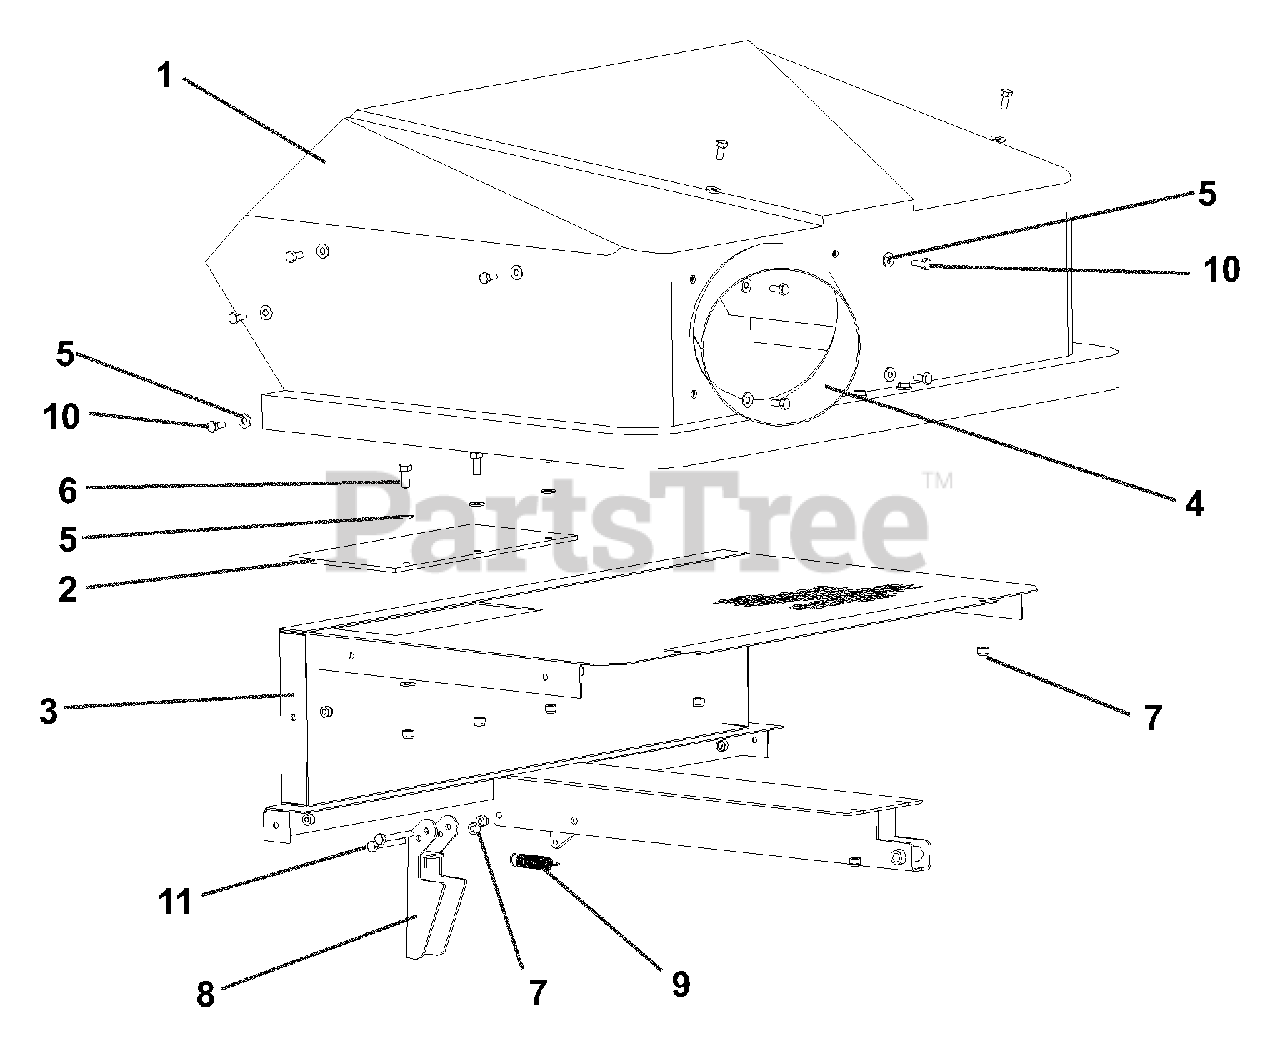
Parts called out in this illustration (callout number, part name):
1	Top, Plastic
2	Rubber Flap
3	Top Insert
5	Washer, Flat, 1/4"
6	Bolt, Hex, 1/4"-20 x 3/4", Gd. 5
7	Nut, Hex, Nylon Lock, 1/4"-20
10	Bolt, Hex, 1/4"-20 x 5/8"
11	Bolt, Hex, 1/4"-20 x 2"
